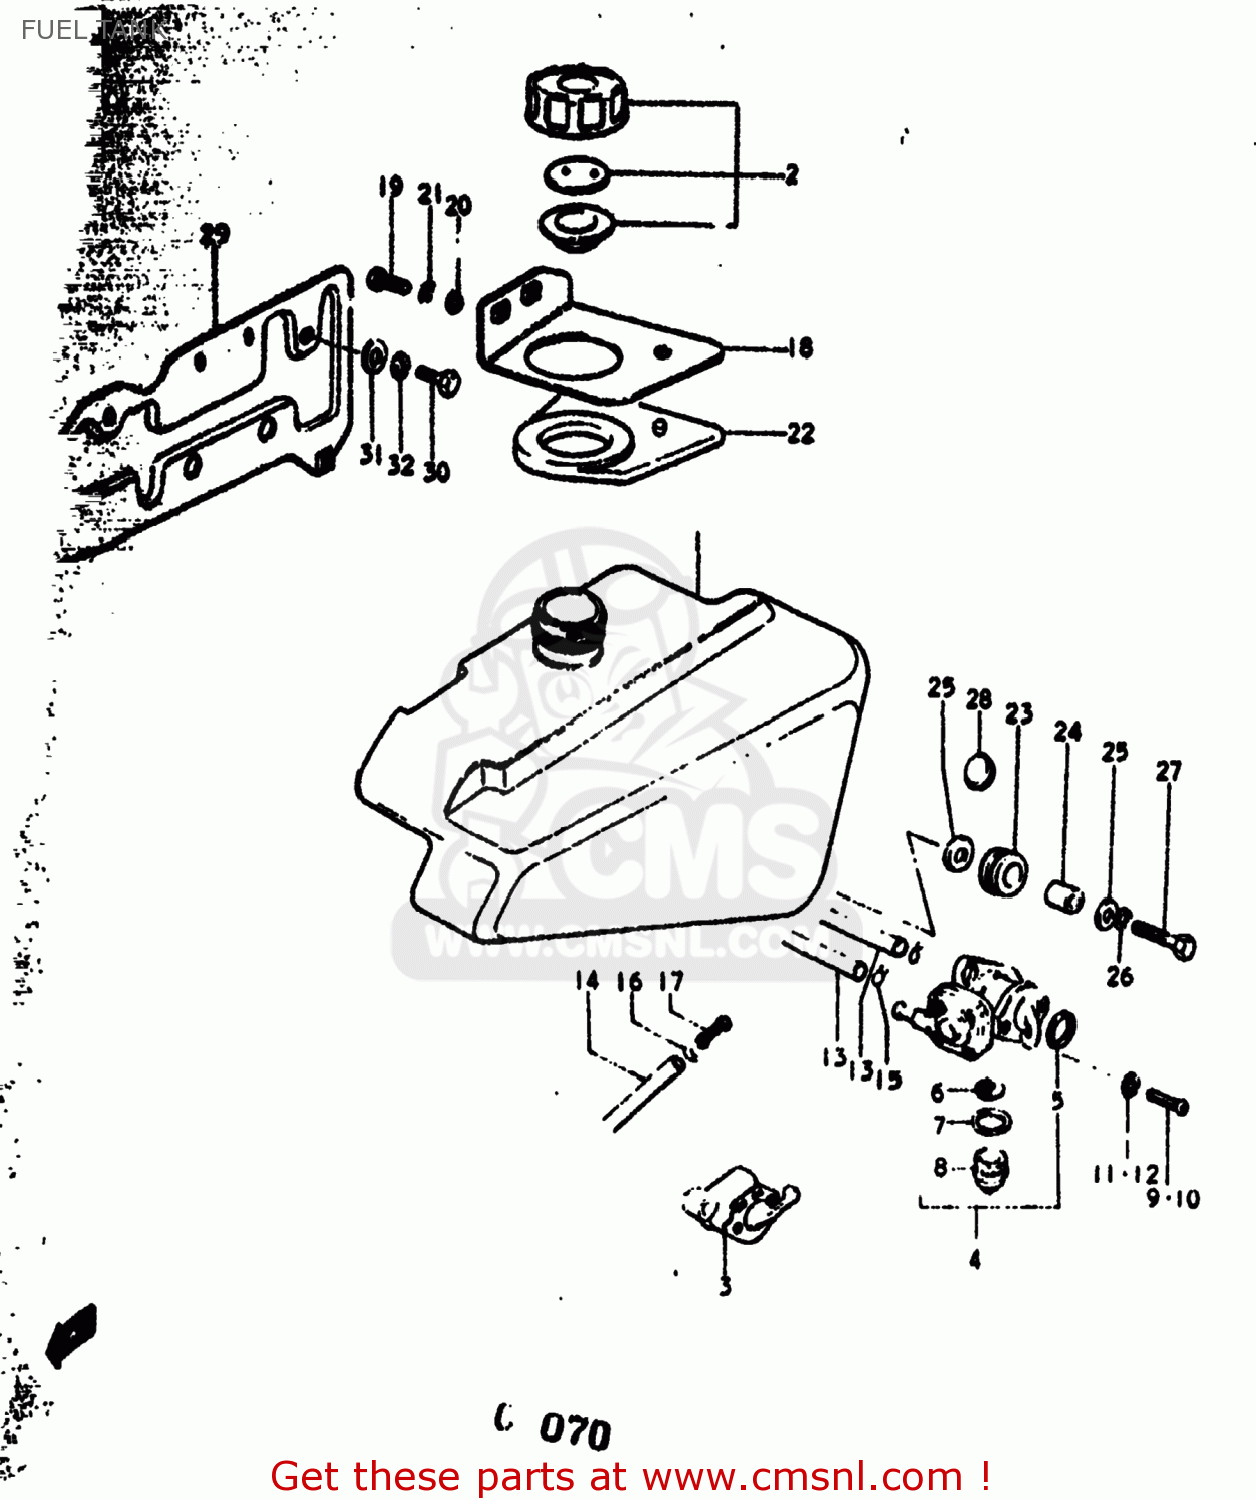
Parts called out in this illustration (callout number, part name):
1	TANK ASSEMBLY,FUEL
2	TANK ASSEMBLY,FUEL
3	COCK ASSEMBLY,FUEL
4	COCK ASSY,FUEL
5	GASKET,LEVER (NAS)
6	NET,FILTER
7	GASKET,CLEANER CUP (NAS)
8	CUP,FUEL COCK
9	SCREW
10	SCREW
11	LOCK WASHER
12	LOCK WASHER
13	HOSE,FUEL
14	HOSE
15	CLIP
16	CLIP
17	FILTER,FUEL
18	PACKING SET,FUEL PUMP
19	BOLT
20	WASHER
21	LOCK WASHER
22	CUSHION,FUEL TANK,UPPER
23	CUSHION
24	SPACER (8.8X12X13.5)
25	WASHER
26	LOCK WASHER
27	BOLT
28	CUSHION
29	PROTECTOR,FUEL TANK
30	BOLT
31	WASHER
32	LOCK WASHER
